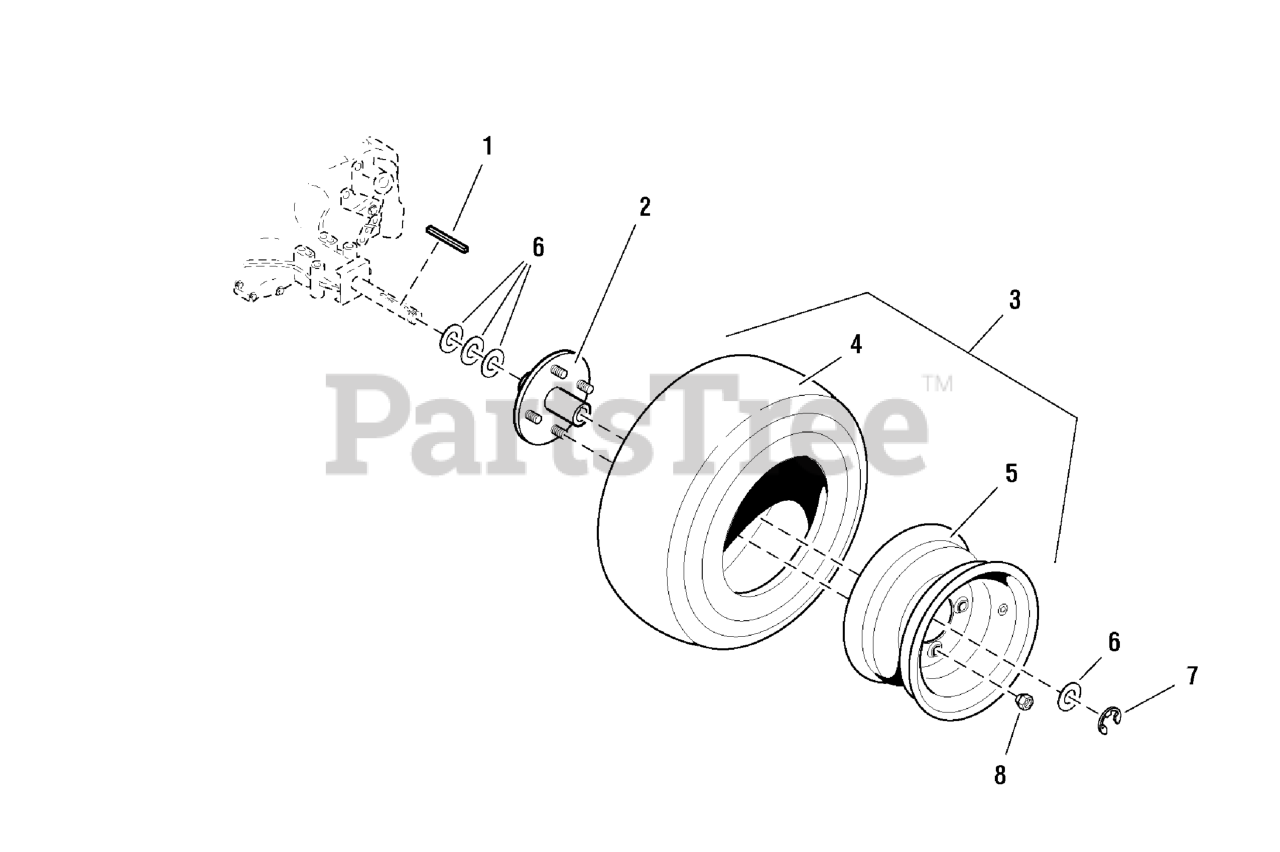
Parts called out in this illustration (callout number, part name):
1	KEY, 3/16" SQ. X 2-1/2
2	DRIVE HUB
4	TIRE, 16. x 6.5 x 8 (SV)
5	WHEEL ASSEMBLY, 8 x 5.38 (SV)
6	SHIM
7	C-CLIP
8	LUG NUT, 1/2-20
